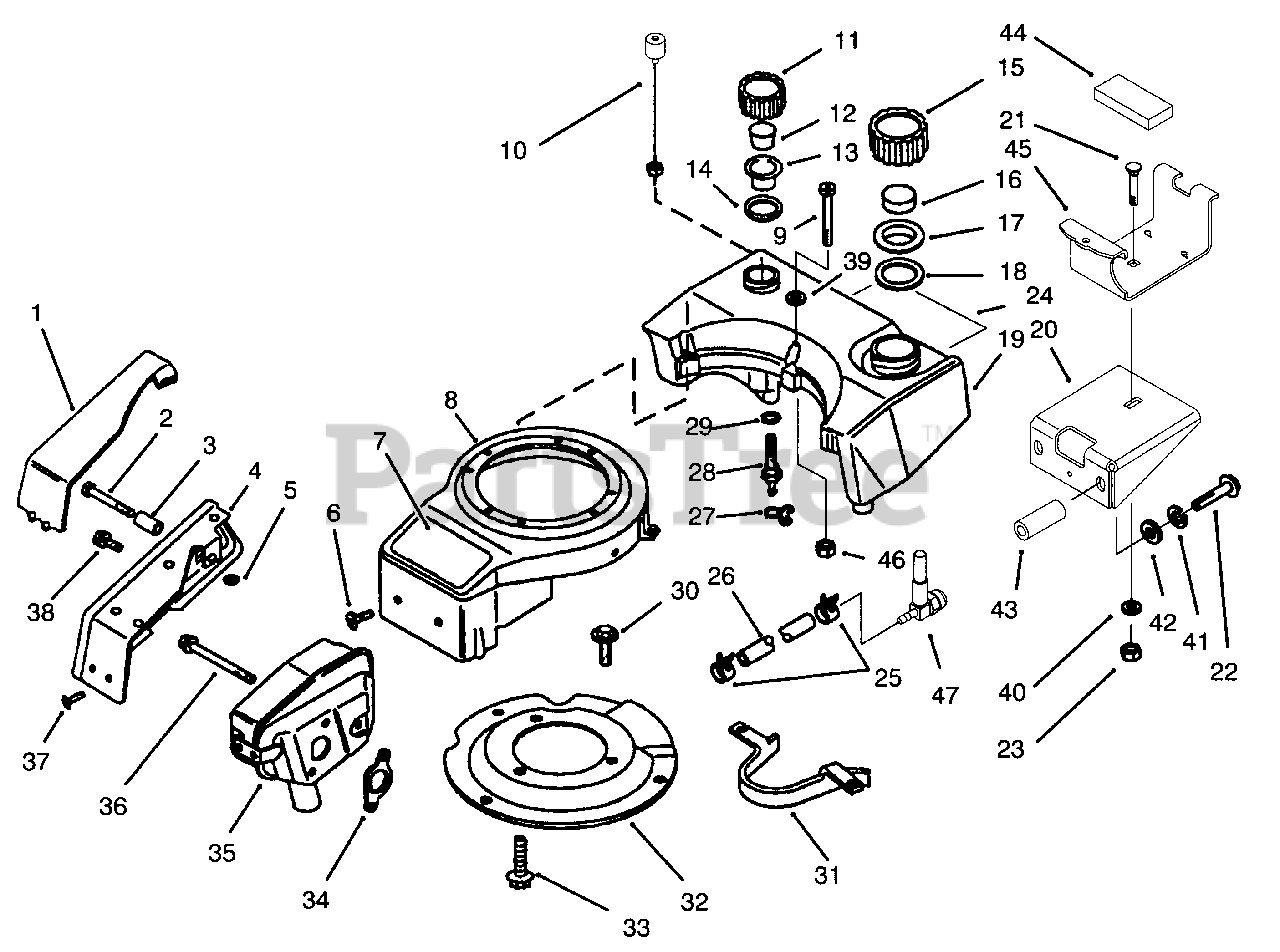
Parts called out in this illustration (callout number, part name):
1	Cover-Muffler
2	Screw-Muffler Guard
3	Spacer-Muffler Guard
4	Assembly-Muffler Guard (Incl. Ref. No. 1 & 5)
5	Pushnut
6	Screw-Shroud
7	Decal-Engine
8	Assy-Shroud (Incl. Ref. No. 7)
9	Screw-Fuel Tank
10	Switch-Low Oil
11	Assembly-Oil Cap (Incl. Ref. No 12-14)
13	Cover-Baffle
15	Assembly-Fuel Cap (Incl. Ref. No. 16-18)
17	Cover-Baffle
19	Assembly-Fuel/Oil Tank (Incl. Ref. #10,19,20 24,28-29,43-45,47)
20	Bracket-FuelTank
21	Bolt-Carriage
22	Screw-Bracket To Engine
24	Decal-Fuel Tank
25	Clamp-Fuel Line
26	Fuel Line
27	Clamp-Oil Hose
28	Assembly-Oil Fitting (Incl. Ref. No. 29)
30	Screw-Mtg Plate/Hsg.
31	Snubber-Belt
32	Plate-Engine Mounting
33	Screw-Mtg Plate To Eng.
34	Gasket-Exhaust
35	Muffler
36	Screw-Muffler
37	Screw-Muffler Guard
38	Screw-Muffler Guard
39	Washer-Flat
40	Washer-Flat
41	Washer-Lock
42	Washer-Flat
44	Mount-Fuel Tank
45	Saddle-Fuel Tank
46	Nut-Lock
47	Valve-Fuel Shut-Off
